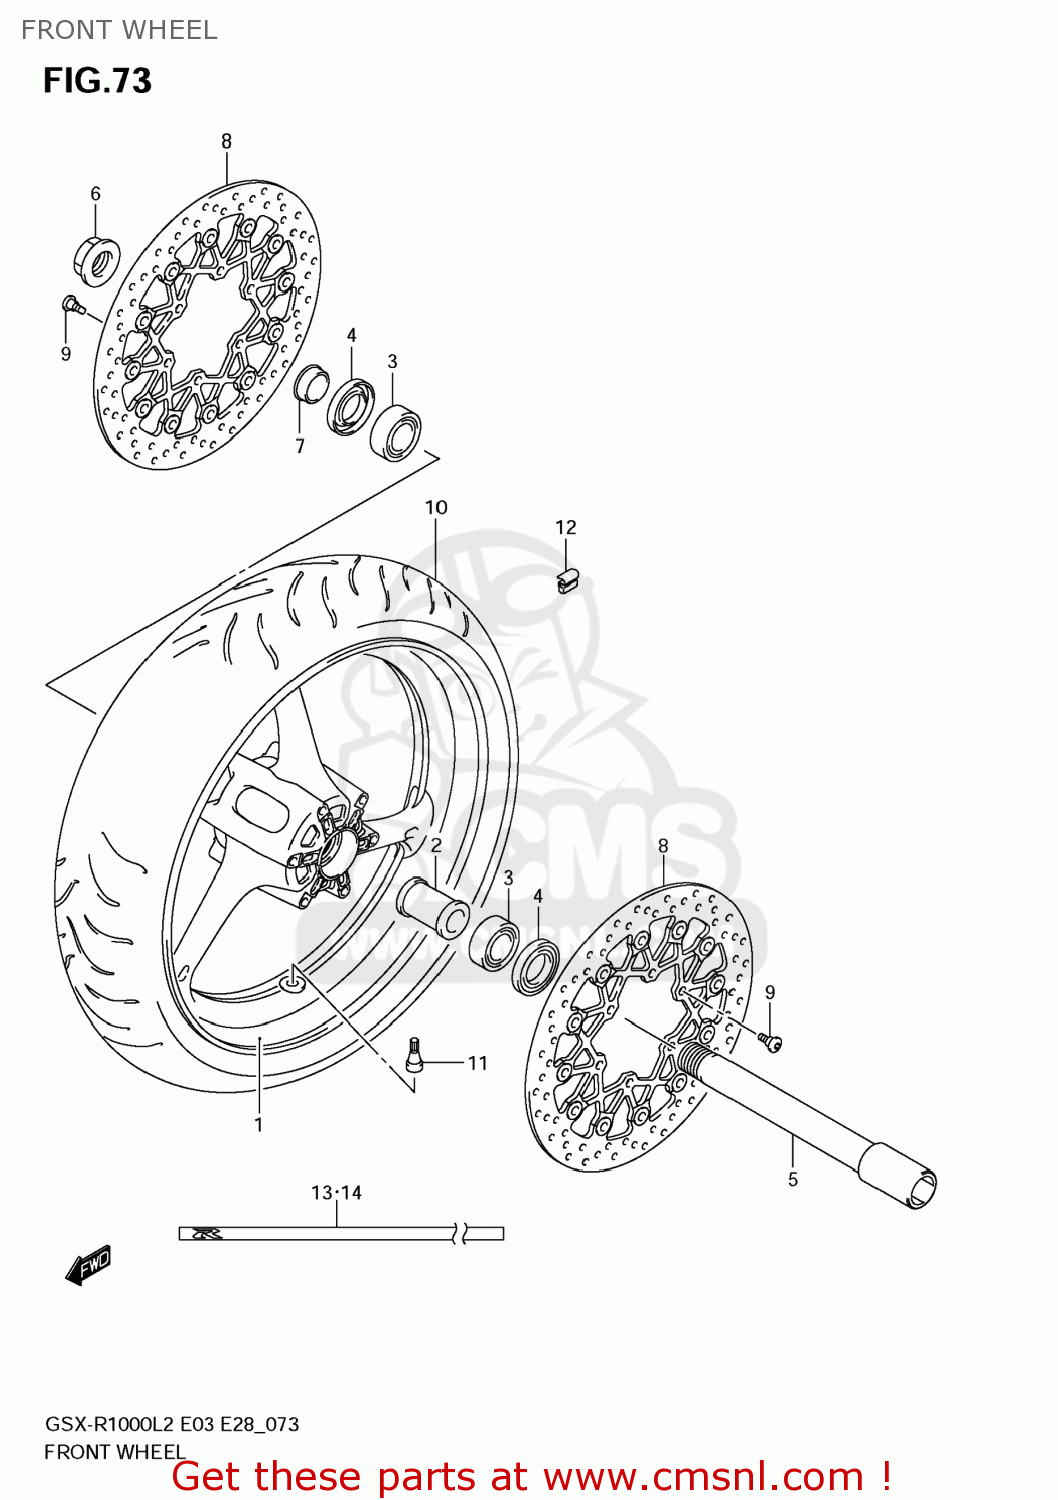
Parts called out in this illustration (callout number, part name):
1	WHEEL,FR(17M/CXMT3.50)
2	SPACER,FR HUB BEARING
3	BEARING(25X52X15)
4	SEAL,OIL(32X52X7)
5	AXLE,FR
6	NUT,FR AXLE
7	SPACER,FRONT A
8	DISC,FR BRAKE
9	BOLT(6X21)
10	TIRE,FR
11	VALVE ASSY,WHEEL RIM(TR412)
12	BALANCER,WHEEL(10G)
13	TAPE,WHEEL FR,R
14	TAPE,WHEEL FR,L
